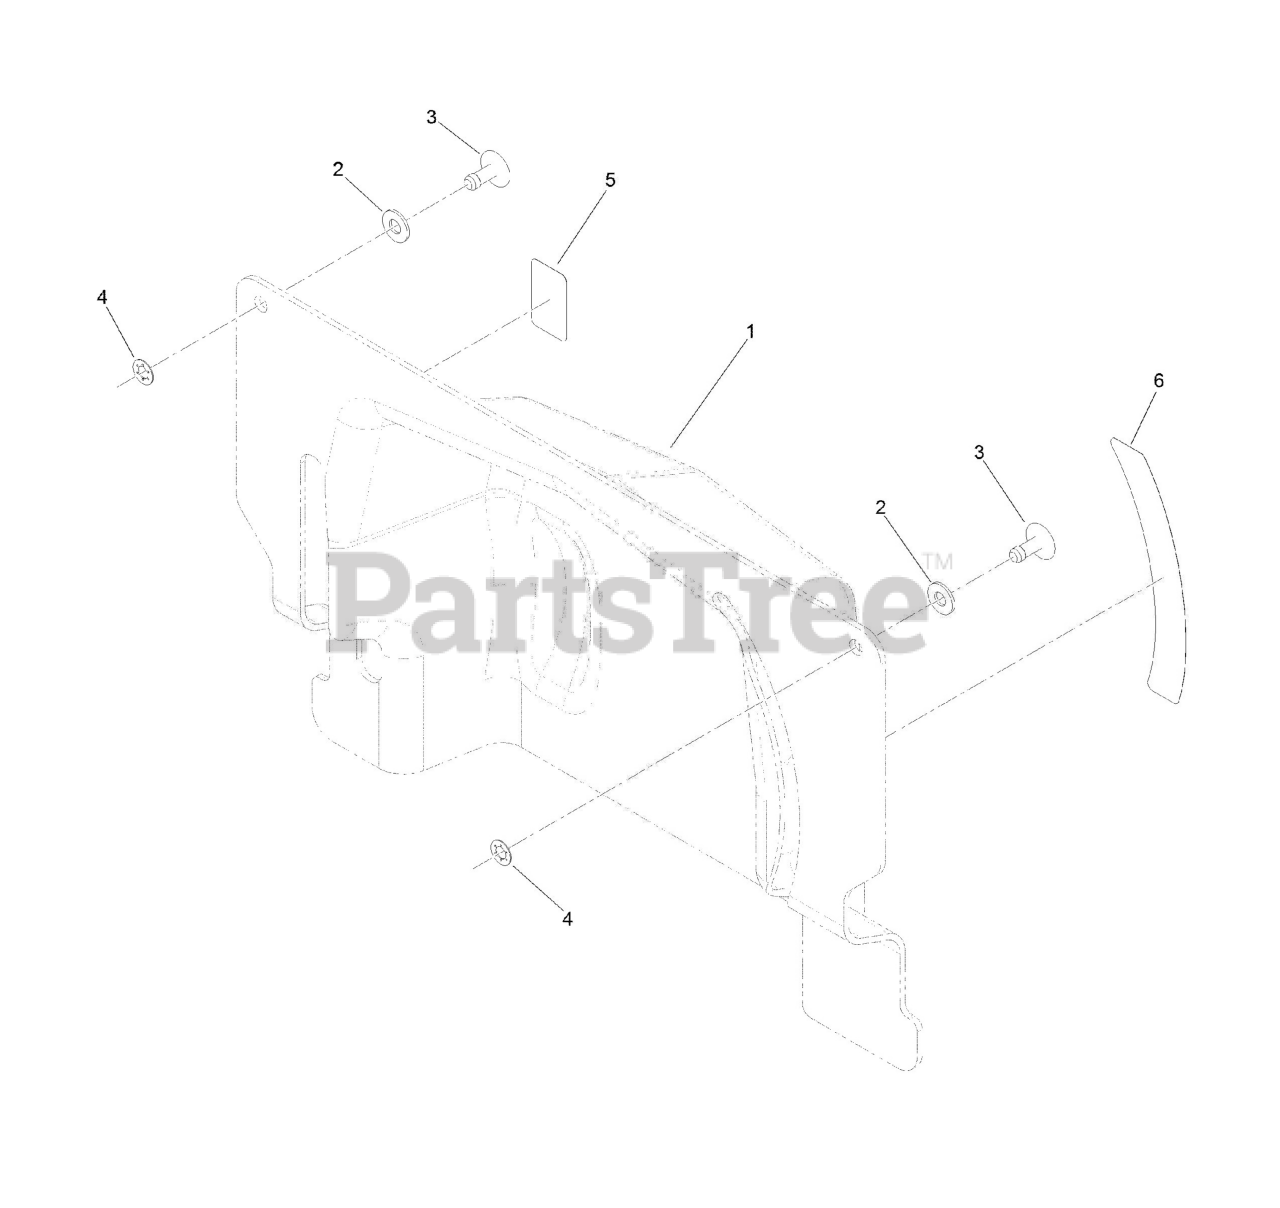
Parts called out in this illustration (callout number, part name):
1	Cover-Transaxle
2	WASHER-FLAT
3	STUD-1/4 TURN
4	RETAINER-STUD
5	DECAL-BRAKE, PARK
6	DECAL-RELEASE, DRIVE
